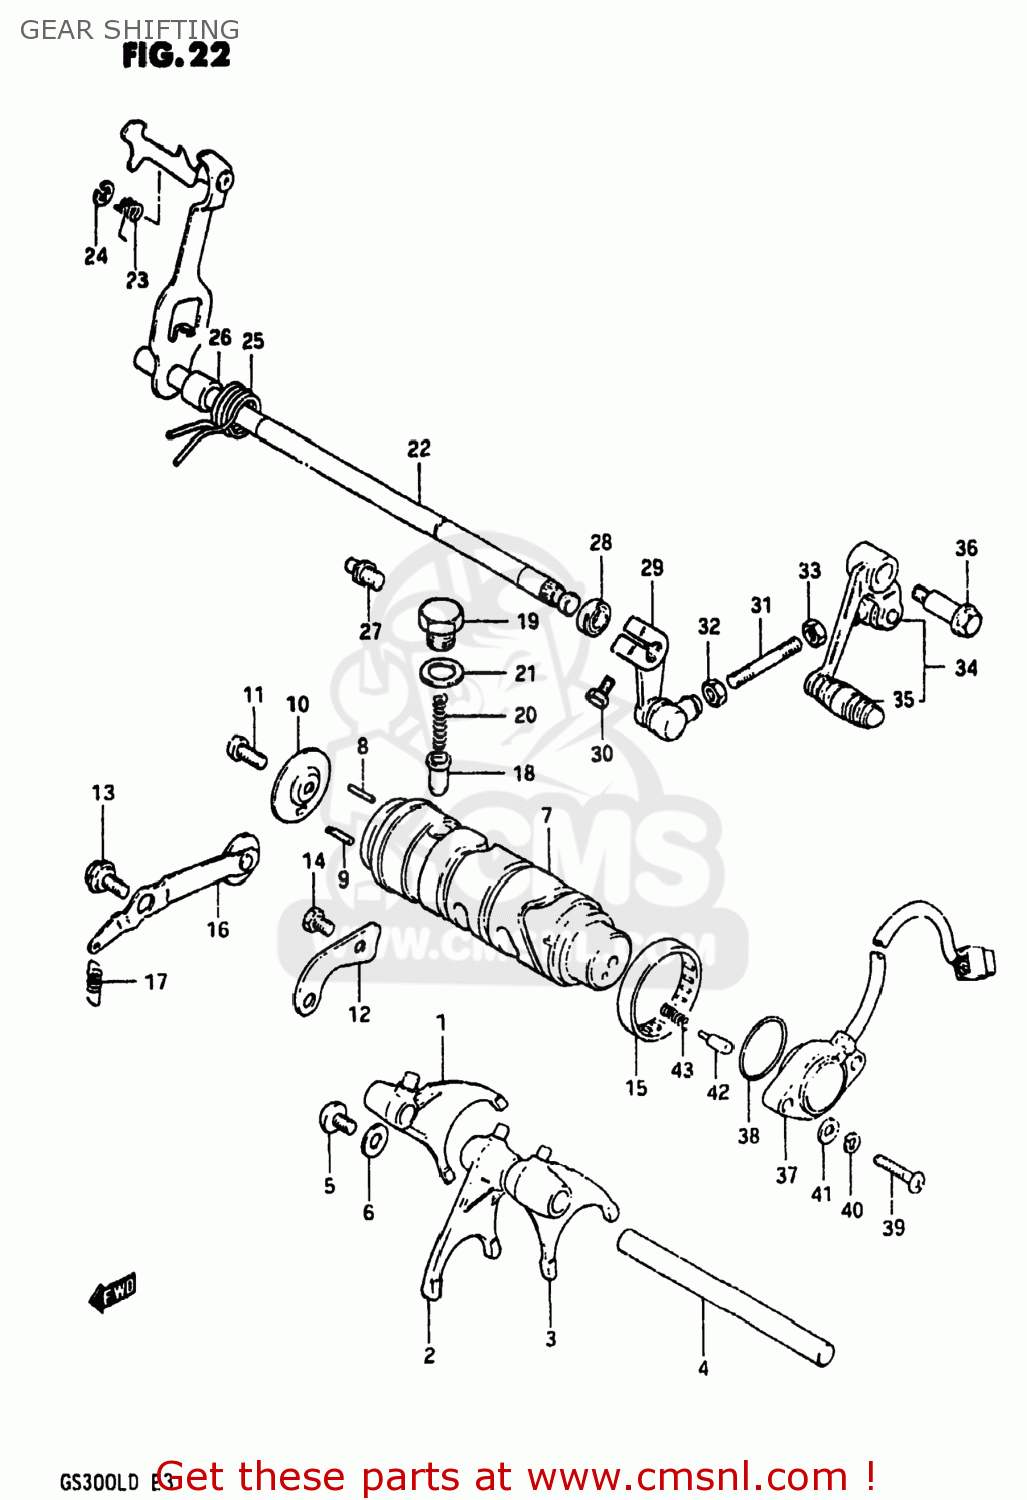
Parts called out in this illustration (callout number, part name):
1	FORK,GEAR SHIFT NO.1
2	FORK,GEAR SHIFT NO.2
3	FORK,GEAR SHIFT NO.3
4	SHAFT,GEAR SHIFT FORK
5	SCREW
6	WASHER
7	CAM,GEAR SHIFT
8	PIN(4X18.5)
9	PIN
10	RETAINER,GEAR SHIFT CAM DR PIN
11	SCREW
12	GUIDE,GEAR SHIFTING CABLE
13	BOLT
14	BOLT
15	BEARING(40X47X12)
16	STOPPER,GEAR SHIFTING
17	SPRING
18	STOPPER,GEAR SHIFT CAM NO.2
19	HOLDER,GEAR SHIFT CAM STOP SPR
20	SPRING
21	GASKET(14X19.2X2) (NAS)
22	SHAFT,GEAR SHIFT
23	SPRING
24	E RING
25	SPRING
26	SPACER(12X20X15.3)
27	STOPPER,GEAR SHIFT CAM
28	OIL SEAL
29	ARM,GEAR SHIFT LINK
30	BOLT
31	ROD,GEAR SHIFT LINK
32	NUT
33	NUT
34	LEVER ASSY,GEAR SHIFT
35	RUBBER,GEAR SHIFT PEDAL
36	SHAFT,GEAR SHIFT LEVER
37	BASE ASSEMBLY,NEUTRAL SWITCH TERMINAL
38	O-RING (D:2.4 ID:26.2)
39	SCREW 5X20
40	LOCK WASHER
41	WASHER
42	PIN(5X15.5)
43	SPRING
